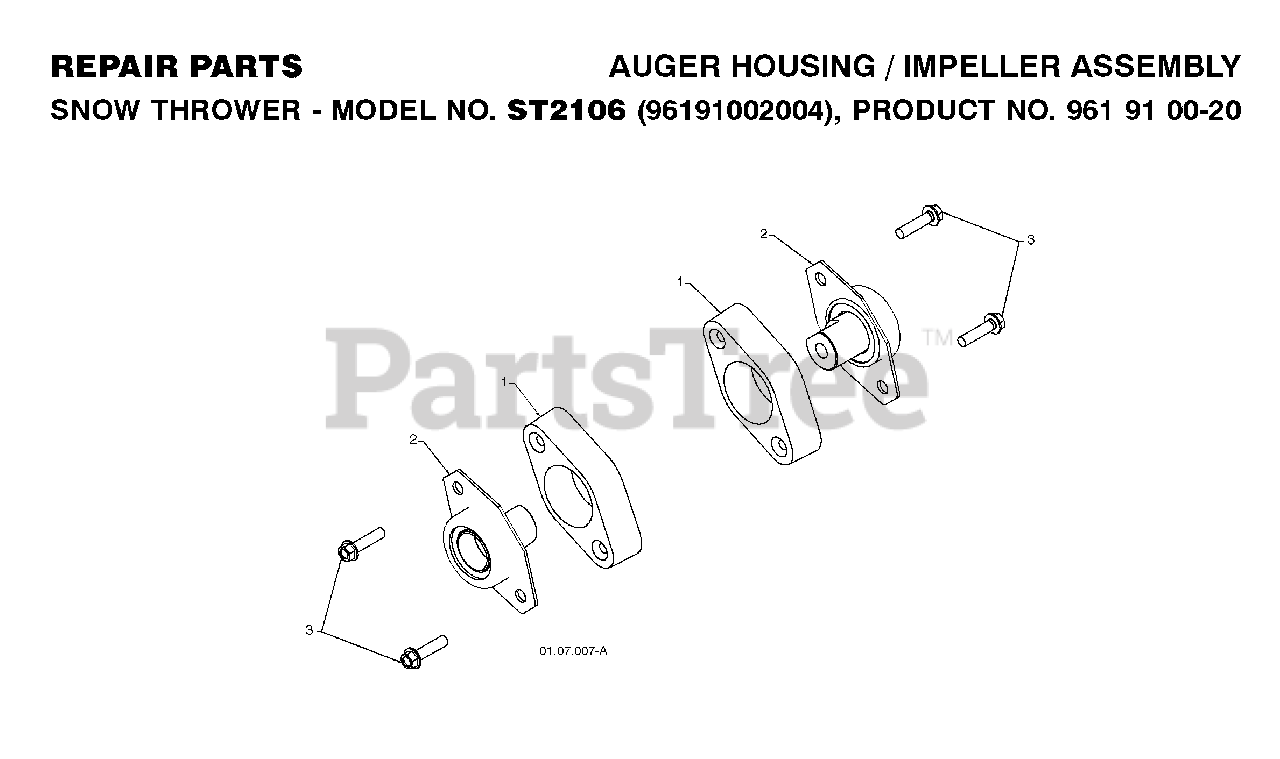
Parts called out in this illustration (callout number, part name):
1	BEARING RETAINER, PLASTIC
2	BEARING.BALL.AUGER
3	SCREW, HEX HD 5/16X1
